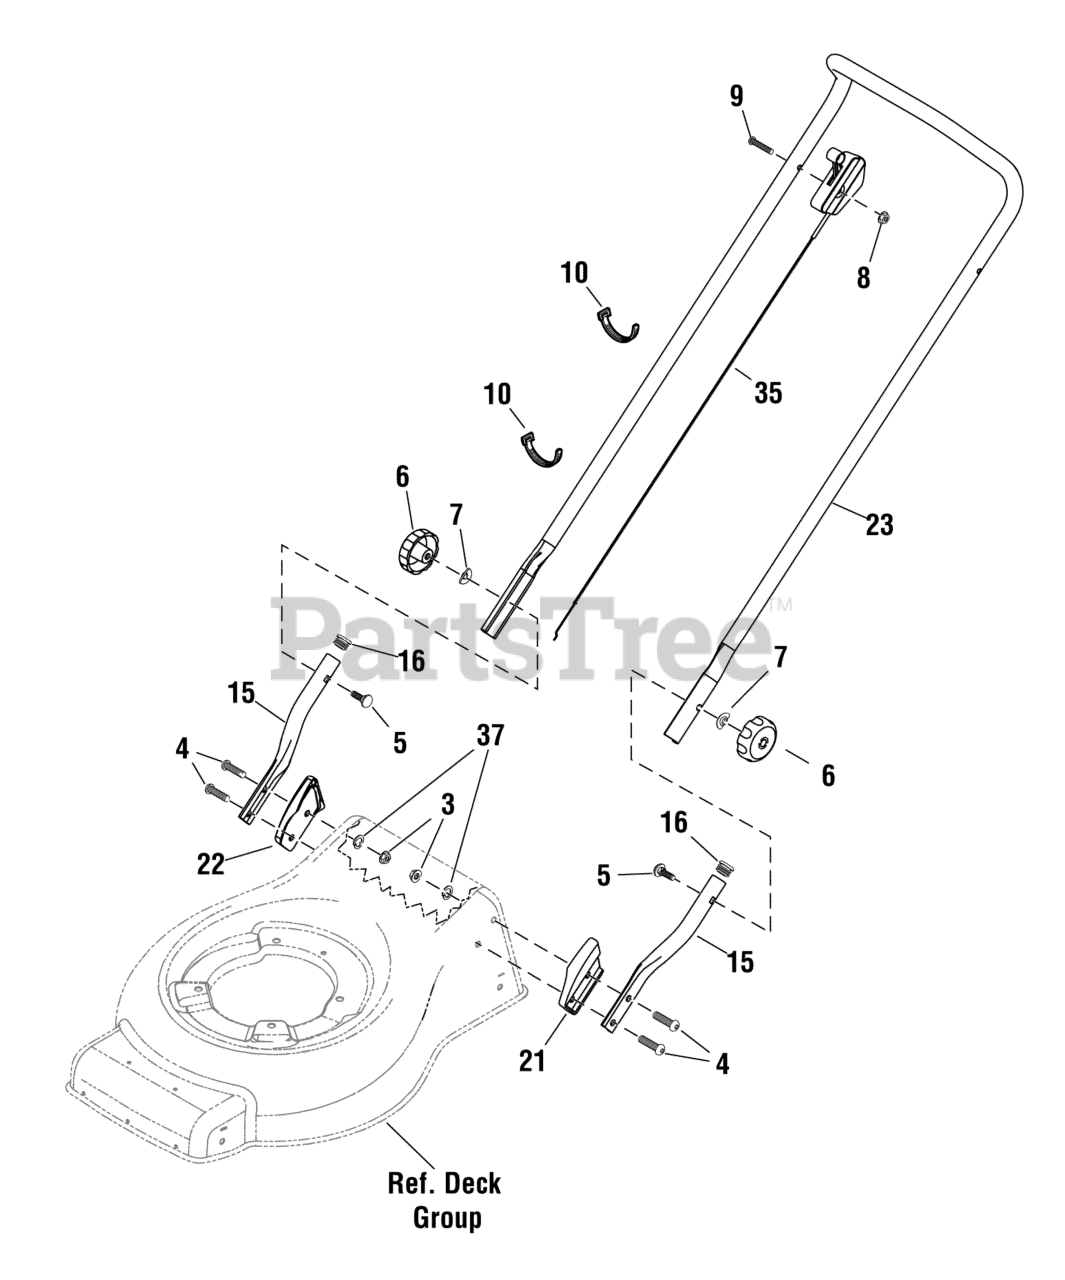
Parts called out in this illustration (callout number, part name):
3	NUT, Lock, Nylon, M8 - 1.25
4	BOLT, Hex Key Head, M8 x 1.25
5	BOLT, Carriage, M8 x 1.25
6	KNOB, M8 x 1.25
7	WASHER, Formed
8	NUT, Hex Lock, M6 x 1
9	SCREW, Button Head, M6 x 1
10	TIE, Cable
15	HANDLE, Lower
16	PLUG, 7/8
21	BRACKET, Handle Mount, LH
22	BRACKET, Handle Mount, RH
23	HANDLE, Upper
35	THROTTLE CABLE ASSEMBLY
37	WASHER, Split Lock
